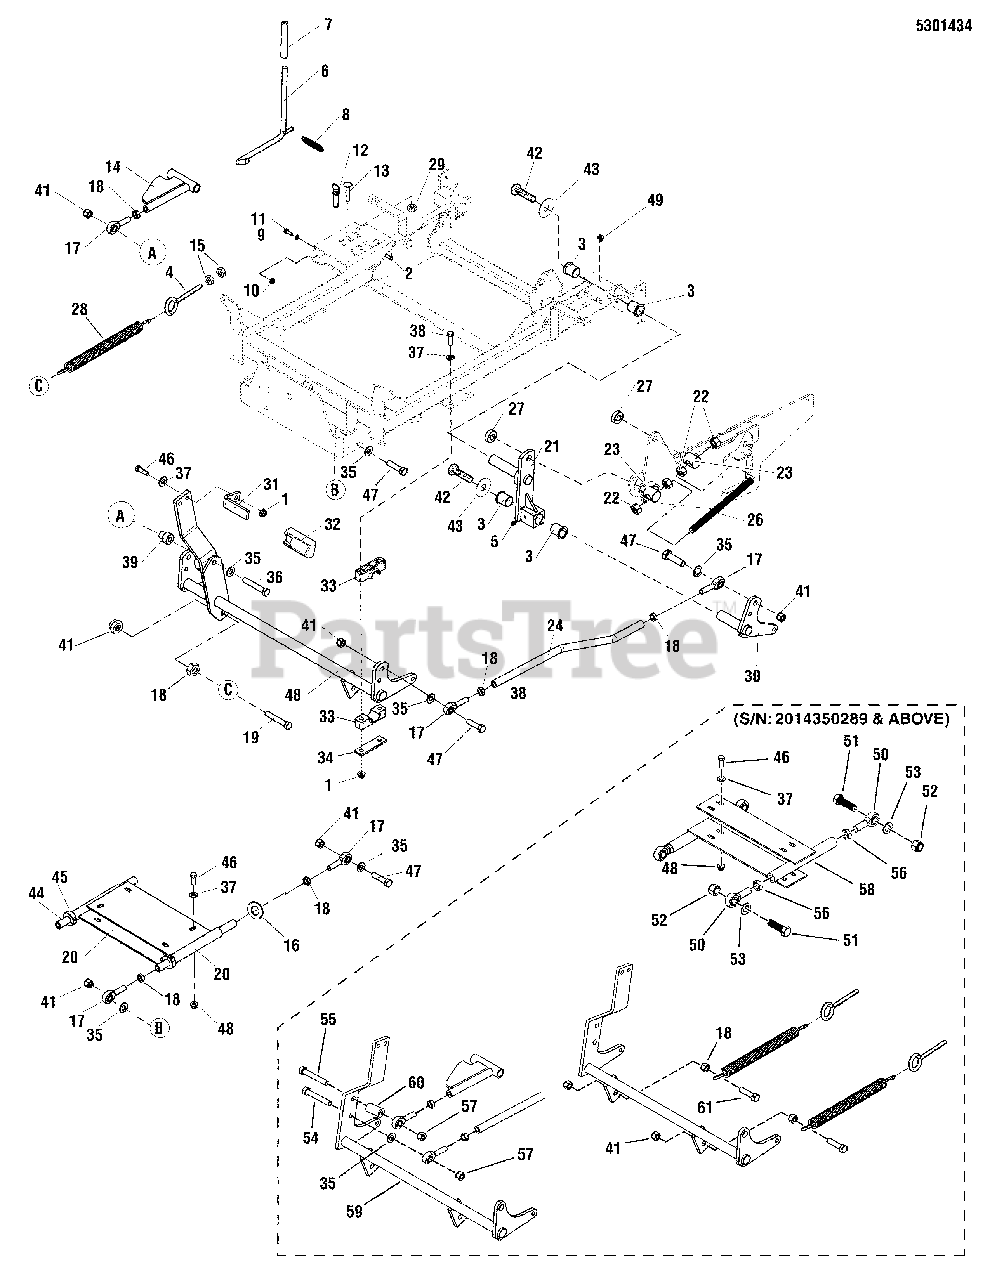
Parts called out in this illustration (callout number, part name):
1	NUT, 3/8-16 HEX NYLOCK FLANGE
2	PIN, CLEVIS, 1/4 X 1/2
3	BUSHING, 1.00 X 1.13 X 1.38, PLASTIC
4	EYE BOLT, 3/8-16 X 6, 3.0 THRD, 1 EYE
5	GREASE FITTING, 1/4-28 STRAIGHT
6	WELD, ROD DECK LIFT - BLK
7	GRIP, FOAM
8	SPRING, EXTENSION
9	WASHER, 1/4 SAE (5025154)
10	NUT, 1/4-20 HEX SERR. FLANGE
11	BOLT, 1/4-20 X 3/4 GD5 YZ
12	PIN, HITCH, 1/2 X 2.00 OAL, YP
13	BOLT, 3/8-16 X 2, CARRIAGE
14	WELD, DECK ADJUST LINK - ORG
15	NUT, 3/8 JAM
16	WASHER, 1/2 SAE
17	BALL JOINT, 1/2-20, MALE
18	NUT, 1/2-20 HEX JAM
19	BOLT, 1/2-13 X 2-1/4 GD5 YZ
20	WELD, DECK STABILIZER - BLK
21	WELD, REAR LIFT, LH - BLK
22	NUT, 5/8-11 HEX
23	PIVOT, SPRING ROD
24	ROD, DECK LIFT BENT
26	ROD, 5/8-11 X 9.00
27	COLLAR, 5/8 SPLIT
28	SPRING, DECK LIFT ASSIST
29	NUT, 3/8-16 HEX SIDE LOCK
30	WELD, DECK LIFT LEVER, LH - BLK
31	PEDAL, FOOT - BLK
32	RUBBER, FOOT PEDAL
33	PIVOT BLOCK, PLASTIC
34	PLATE, PIVOT BLOCK SUPPORT - BLK
35	WASHER, 1/2 GD9 YZ
36	BOLT, 1/2-13 X 3-1/2 GD5
37	WASHER, 3/8 SAE
38	BOLT, 3/8-16 X 2-3/4 GD5 YZ
39	ADAPTER, CASTER AXLE
41	NUT, 1/2-20 HEX NYLON LOCK
42	BOLT, 3/8-16 X 3/4, GD5, YZ WITH PATCH
43	WASHER, .390 X 1.50 X .109, YZ
44	SHAFT, DECK STABILIZER
45	COLLAR, 3/4 SPLIT
46	BOLT, 3/8-16 X 1 GD5 YZ
47	BOLT, 1/2-20 X 1-3/4 GD5 YZ
48	WELD, DECK LIFT SHAFT - ORG
49	GREASE FITTING, 1/4-28, 90 DEGREE
50	BALL JOINT, 3/4-16, MALE
51	BOLT, 3/4-16 X 2-1/2 YZ GD5
52	NUT, 3/4-16 HEX NYLON LOCK
53	WASHER, 3/4 SAE
54	BOLT, 1/2-13 X 3-1/2 GD5 YZ
55	BOLT, 1/2-13 X 4 GD5 YZ
56	NUT, 3/4-16 HEX JAM
57	NUT, 1/2-13 HEX SIDE LOCK
58	WELD, DECK STABILIZER, IS1500ZX - BLK
59	WELD, DECK LIFT SHAFT - RED
60	SPACER, .52 X 1.00 X 1.75
61	BOLT, 1/2-13 X 2 GD5 YZ
